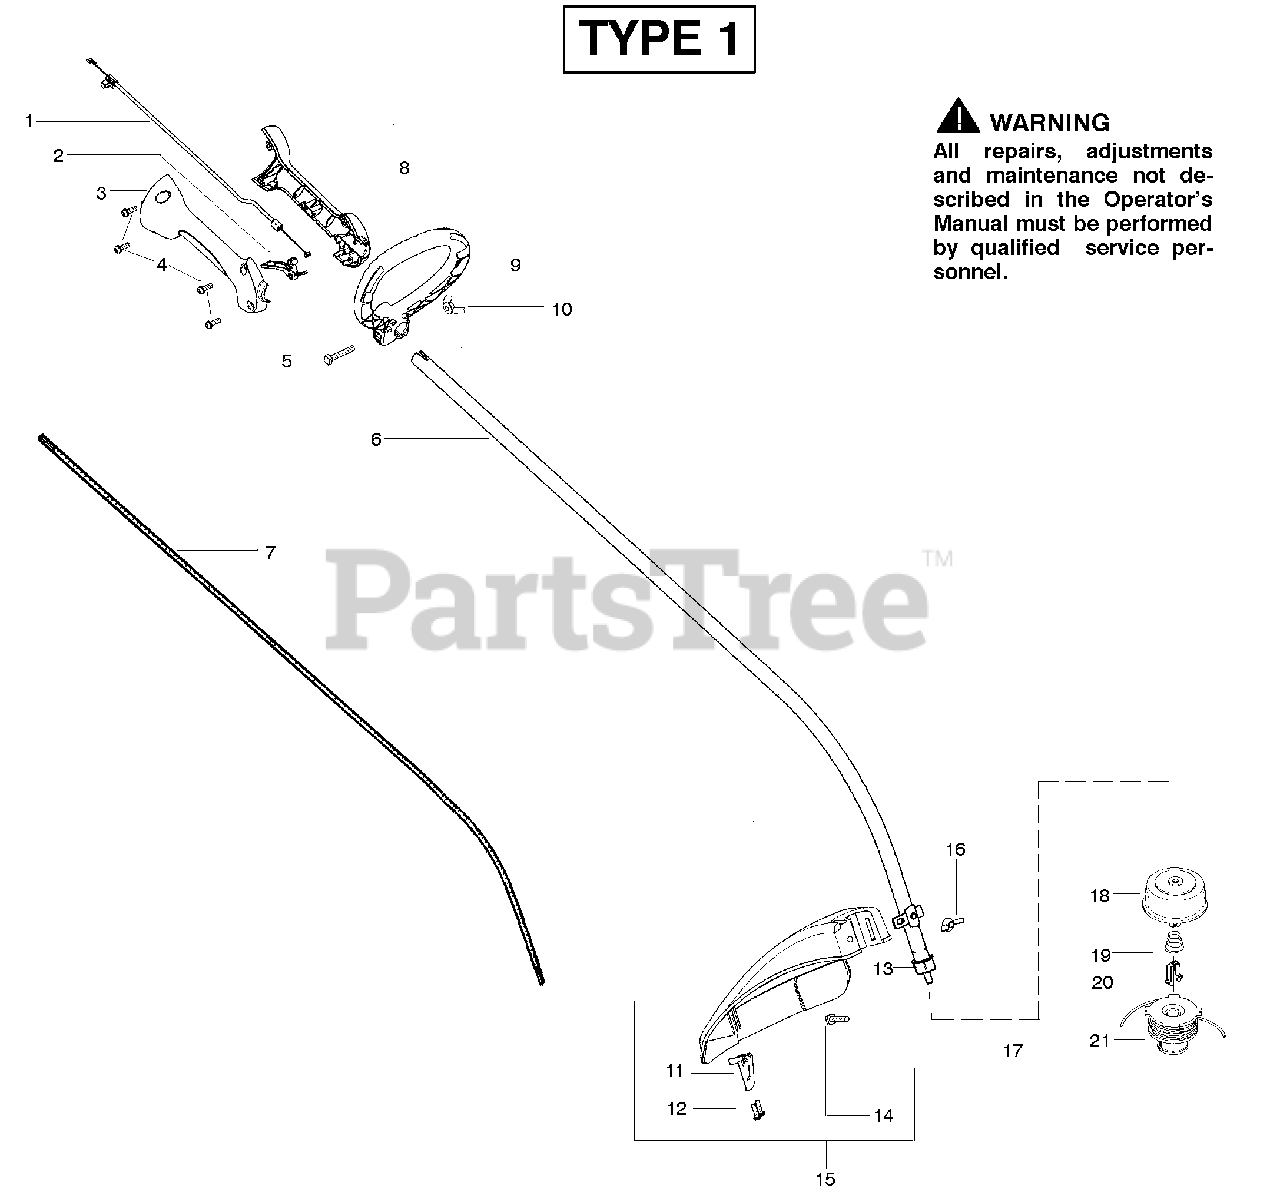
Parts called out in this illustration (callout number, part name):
1	Assy-Throttle Cable
3	Throttle Hsg. (Right)
4	Screw-Throttle Hsg.
5	Bolt-Handle/Shield
6	Assy-Drive Shaft Hsg.
7	Shaft- Flex
8	Throttle Hsg. (Left)
9	Handle-Assist
10	Wingnut
11	Line Limiter
12	Screw-Line Limiter
13	Dust Cup
15	Kit-Shield Assy
16	Wingnut
17	Accy-TNG VI Cutting Head
18	Assy-Hub
19	Spring-Compression
20	Clip-Retainer-Head
21	Accy- Spool w/Line
